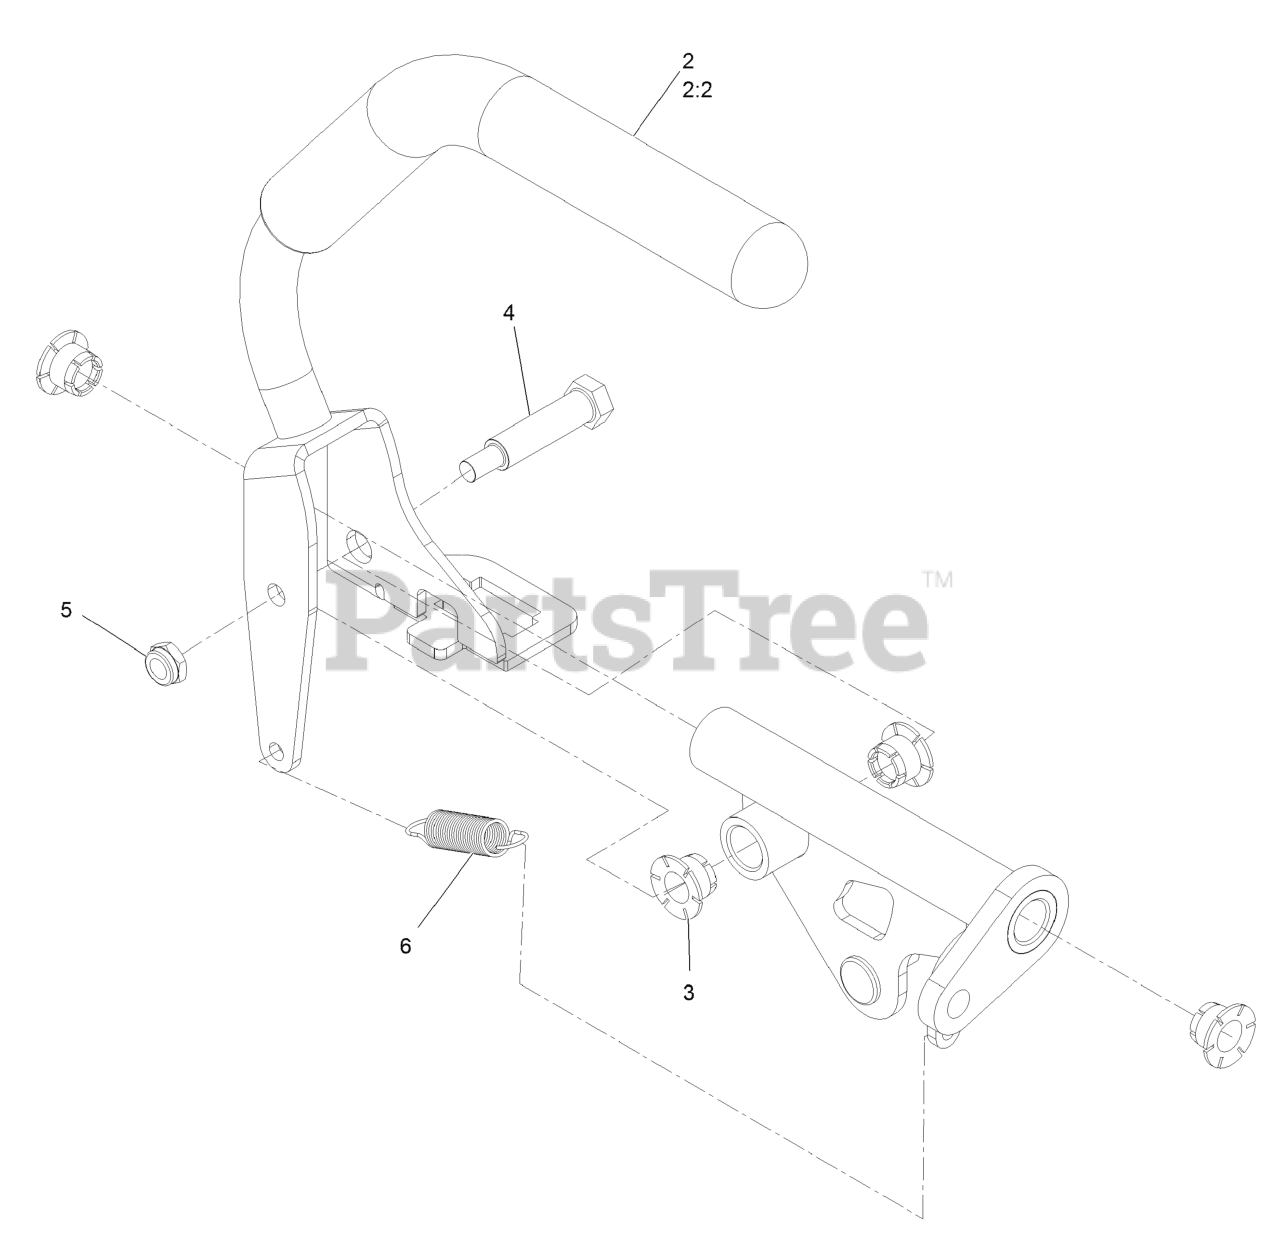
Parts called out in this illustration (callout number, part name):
2	ASM, LT CONTROL LEVER W/ GRIP
2:2	GRIP, DRIVE LEVER
3	BEARING, IGUS
4	BOLT-SHOULDER
5	NUT-LOCK, NI
6	SPRING-EXTENSION
